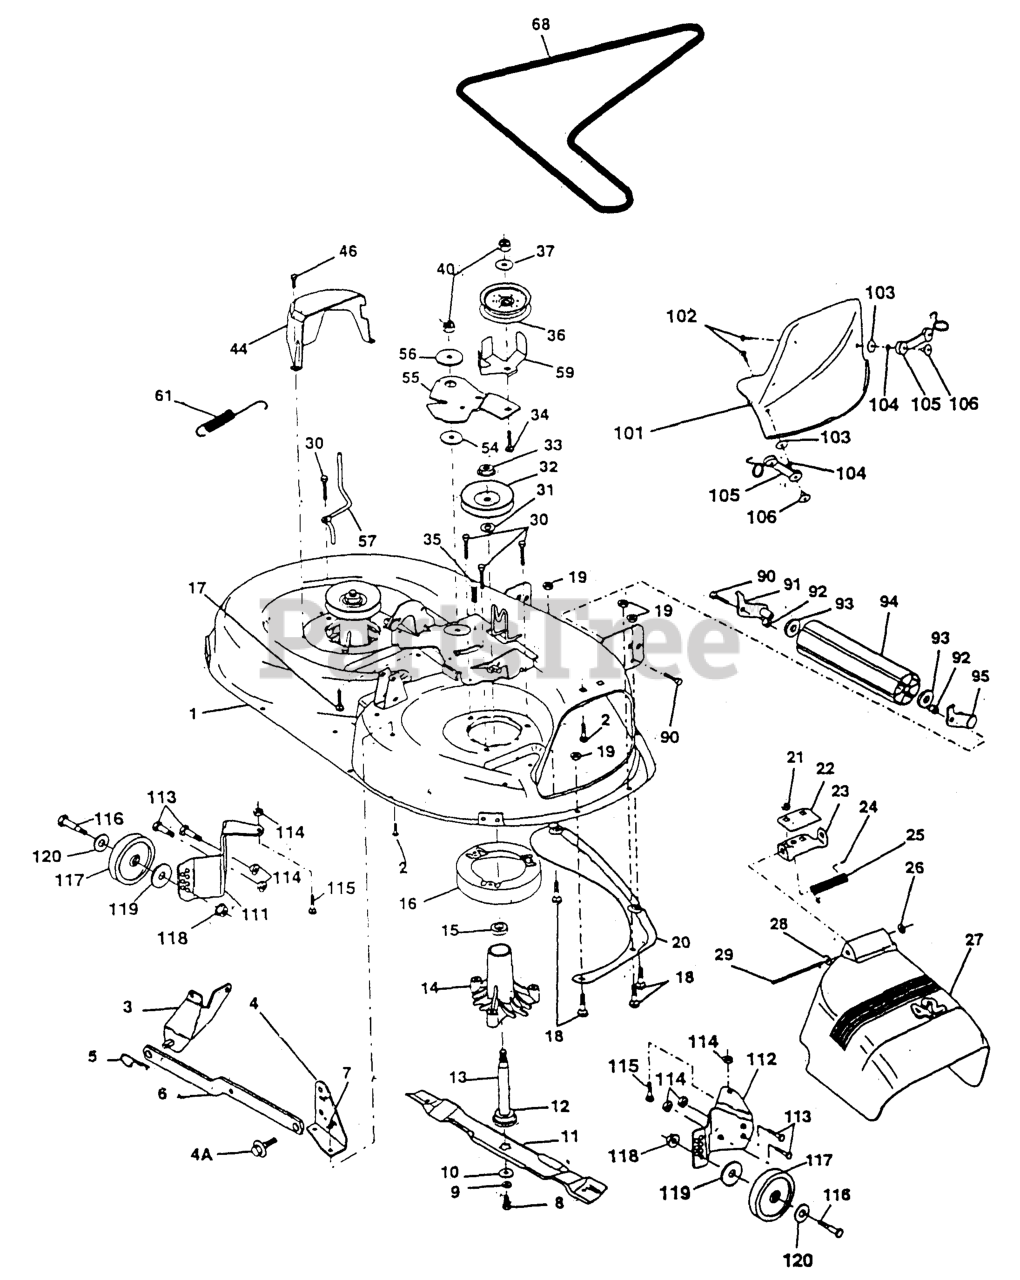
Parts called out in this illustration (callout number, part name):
1	DECK ASM MWR 42"
2	RP BOLT 5/16-18 X3/4 ZN/YEL GR
3	BRKT ASM SWAY BAR
4	BRKT DECK SW BAR
4A	BOLT SHD 5/16-18
5	RETAINER-SPRNG RB
6	REAR SUSP ARM
7	NUT.71038.31-18.HEX.NYLOCK
8	BLADE BOLT
9	LOCKWASHER
10	WASHER.BLADE
11	BLADE.42".MULCH
12	BEARING.BALL.#6204.(MANDREL)
13	SHAFT ASM VENT
14	HOUSING.MANDREL.VENTED (MACHD)
16	STRIPPER
17	BOLT
18	BOLT
19	NUT.71038.31-18.HEX.NYLOCK
20	BAFFLE
21	NUT.71038.31-18.HEX.NYLOCK
22	STIFFENER BRACKET
23	DEFLECTOR BRACKET
24	CAP-SLEEVE LT
25	SPRING TORSION
26	NUT PUSH M
27	SHIELD.DEFLECTOR.MOWER.42".BLK
28	Washer 11/32 X 5/8 X 16 Ga
29	ROD.HINGE
30	SCREW
31	WASHER
32	MANDREL PULLEY
33	NUT
35	FASTENER.XMAS.TREE
36	FLAT IDLER PULLEY
37	WASHER
40	NUT
41	IDLER SPRING SPACER
44	GUARD MANDREL LH BLACK
46	SCREW.1/4-20X5/8
54	HARDENED WASHER
55	IDLER ARM
56	SPACER RETAINER
58	GUARD, BELT
61	SPRING EXTENSION
68	RP.V-BELT
90	BOLT
91	BRACKET LH (A)
93	Washer 17/32 X 7/8 X 16 Ga
94	NOSE ROLLER
95	BRACKET RH (B)
101	COVER MULCH 42"
102	SCREW
103	LOCKWASHER #10
105	LATCH ASSEMBLY
106	WELDNUT
111	BRACKET
112	BRACKET
113	BOLT
114	NUT
115	BOLT.CARR.5/16-18X1/2
116	BOLT M
117	WHEEL.GAUGE.BLK.4.93
118	LOCKNUT
119	WASHER.5/16.FLAT.STE.STD.
120	Washer 17/32 x 15/16 x 12 Ga.
